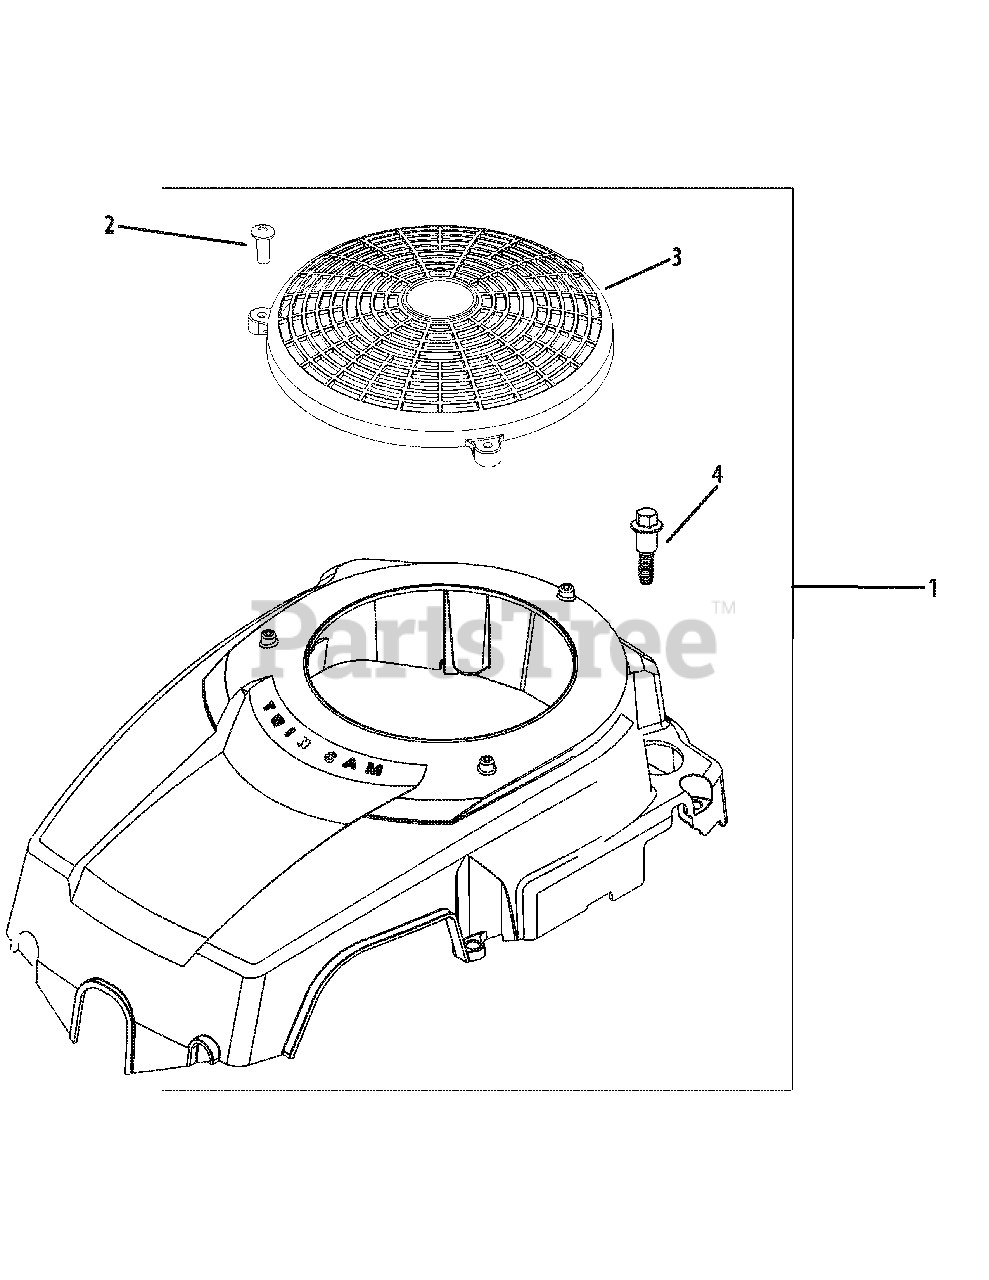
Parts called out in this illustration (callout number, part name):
1	Blower Housing & Guard (Inc. 2-4)
2	Phillips Head Screw, #11-16 X 1/2"
4	Shd Thd Frm Screw, M6 X 1 X 26
